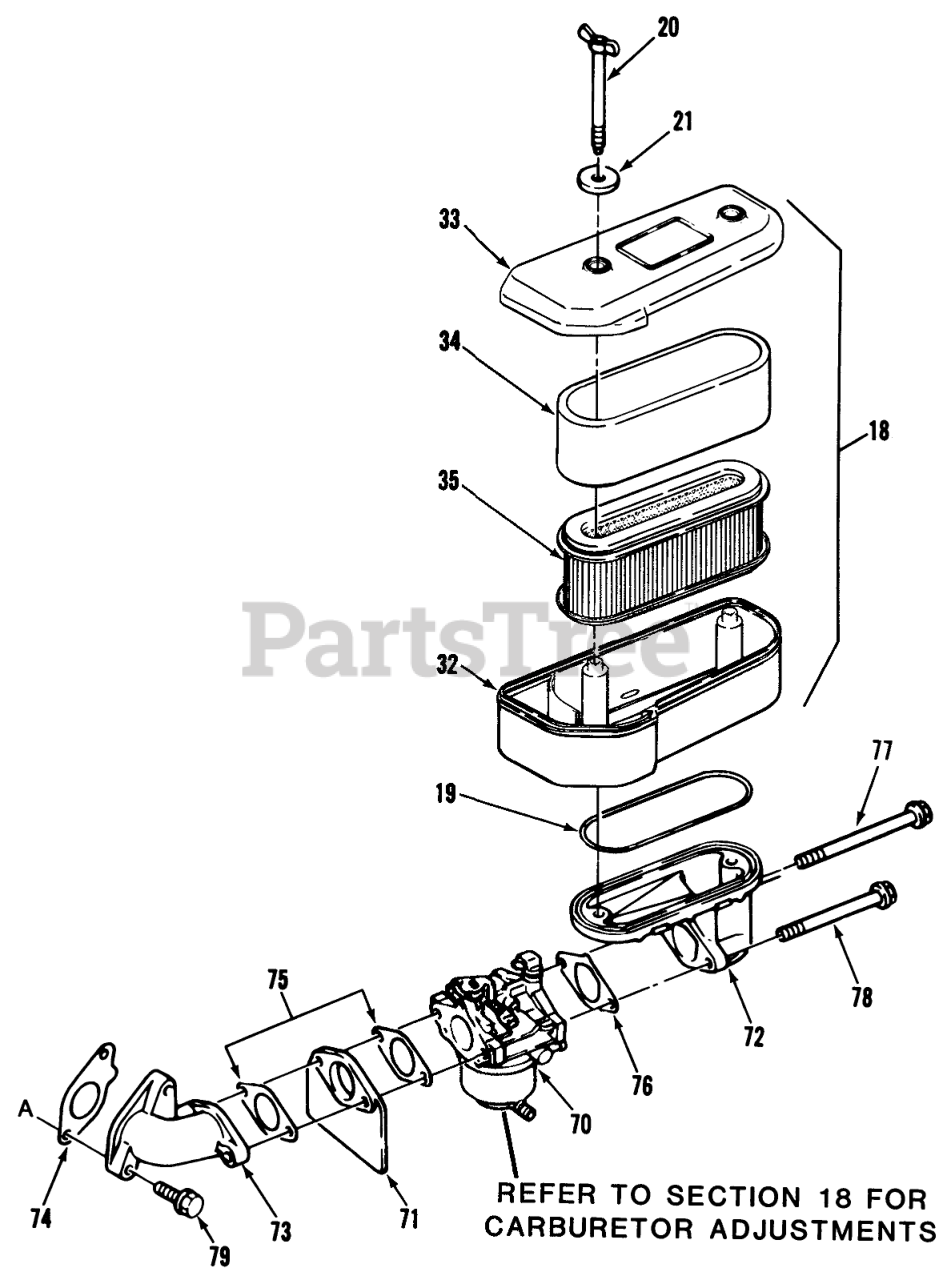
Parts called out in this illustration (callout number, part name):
18	Air Filter Assy (includes items 32, 33, 34 & 35)
19	Gasket
21	Washer
32	CASE-Air Filter
33	CAP-Air Filter
70	Carburetor Assy-see section 9-6 for parts breakdown
72	Pipe-Intake
73	Pipe-Intake
74	Gasket
75	Gasket
76	Gasket
79	Bolt-Flanged (8X25)
